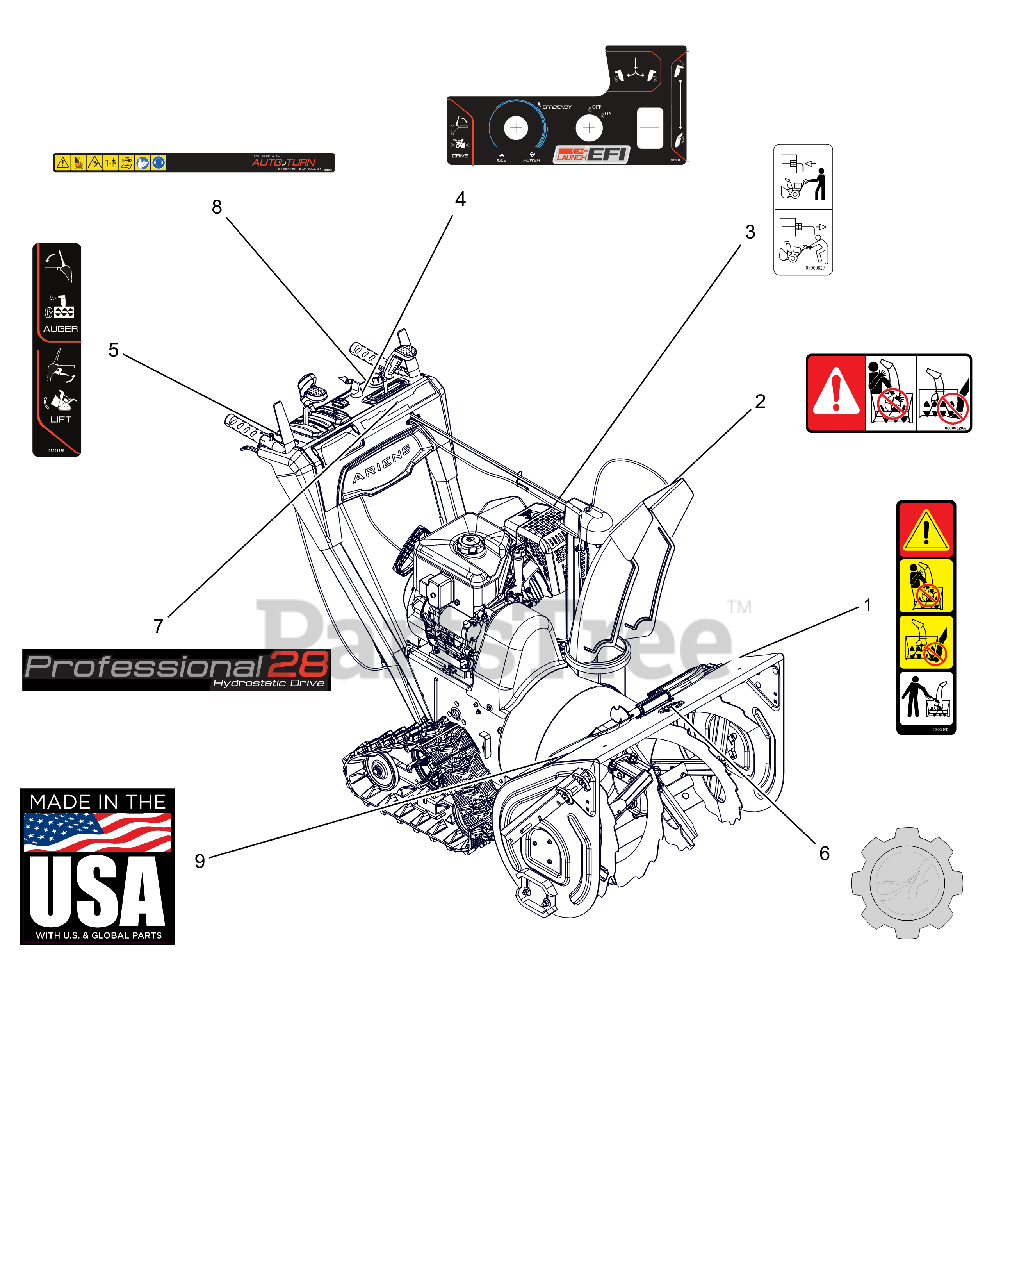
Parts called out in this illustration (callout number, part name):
1	DECAL, DANGER - ROTATING PARTS
2	DECAL, DANGER
3	DECAL, BYPASS
4	DECAL, CONTROL - QT EFI W/GEL
5	DECAL,CONTROL-RH TRACK
6	DECAL, ARIENS-GEAR BADGE -THK
7	DECAL, DASH - PRO HYDRO 28
8	DECAL,DASH - SAFETY/EFI
9	DECAL, MADE IN USA
